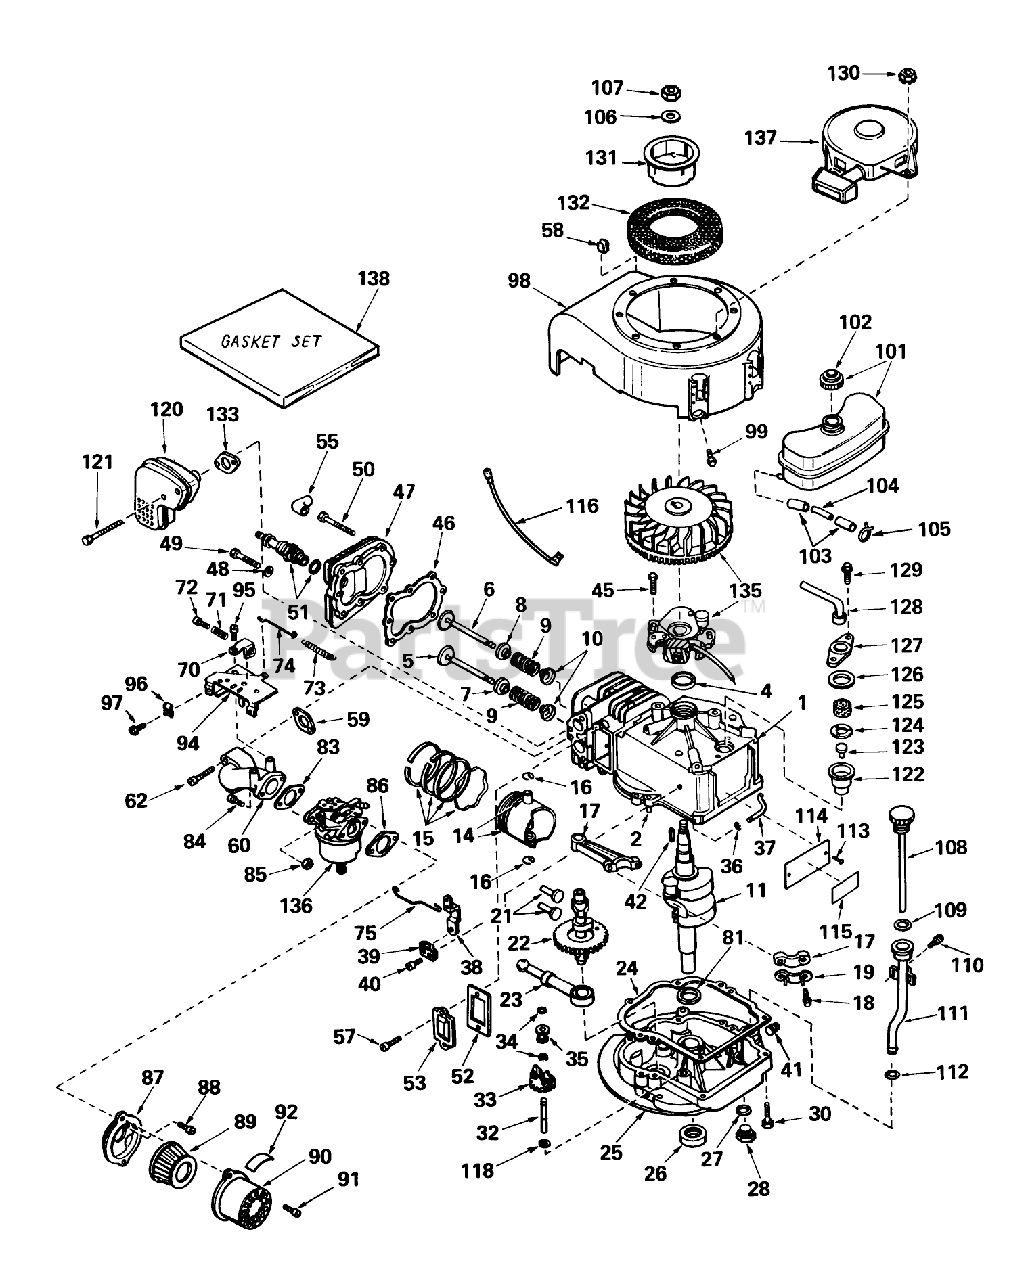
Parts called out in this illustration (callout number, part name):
1	Cylinder Assy. (Incl. Nos. 2 4)
2	Pin-Dowel
4	Seal-Oil
5	Valve, Intake (Standard) (Incl. Nos. 7, 9 10)
5	Valve, Intake (1/32" Oversize) (Incl. Nos. 7, 9 10)
6	Valve, Exhaust (Standard) (Incl. Nos. 8, 9 10)
6	Valve, Exhaust (1/32" Oversize) (Incl. Nos. 8, 9 10)
7	Cap-Upper Valve Spring
8	Cap, Upper Valve Spg (Exhaust)
9	Spring-Valve
10	Cap-Valve, Spring
11	Crankshaft
14	Piston Pin Assy. (Standard) (Incl. 2 of No. 16)
14	Piston Pin Assy. (.010 Oversize) (Incl. 2 of No. 16)
14	Piston Pin Assy. (.020 Oversize) (Incl. 2 of No. 16)
15	Ring Set-Piston Std.
15	Ring Set-Piston .010 oversize
15	Ring Set-Piston .020 oversize
16	Ring-Retaining, Piston Pin
17	Rod Assy., Connecting (Incl. Nos. 18 19)
18	Connecting Rod Bolt
19	Plate Lock
21	Lifter-Valve
22	Camshaft (Compr. Release)
23	Oil Pump ASM
24	Gasket, Mounting
25	Flange Assy., Mounting (Incl. Nos. 26, 27, 28 32)
26	Seal-Oil
27	Gasket-Oil Drain
28	Plug, Drain
30	Screw (1/4-20 x 1-1/4)
32	Shaft-Governor
33	Governor Gear ASM
34	Ring-Retaining
35	Spool-Governor
36	Washer-Flat
37	Rod, Governor (Incl. No. 36)
38	Governor Lever
39	Clamp-Lever, Governor
40	Screw
41	Plug-Pipe
42	Key Flywheel
45	Screw
46	Oil Fill Tube
47	Head Cylinder
48	Washer
49	Screw
50	Screw Hex Hd. Cap
51	Plug, Spark (J17LM or equiv.)
52	Gasket-Breather
53	Cover-Valve
55	Cover-Spark Plug
57	Screw
58	51004 GIL ROTARY TI
59	Gasket, Intake
60	Pipe, Intake
62	Screw, Fil. Slotted Hd.Sems
70	Brachet, Control
71	Spring
72	Screw, Hex Hd.
73	Spring, Governor
74	Link Governor Spring
75	Link Governor
81	Washer-Thrust
83	Gasket
85	Nut and Lock Washer (1/4-28)
86	Gasket
87	Bracket
88	Screw (10-32 x 1/2)
89	Element
90	Body
91	Screw
92	Decal
94	Control Assy., Speed
95	Screw (10-24 x 9/16)
96	Conduit
97	Screw (10-32 x 3/8)
98	Housing, Blower
99	Screw (1/4-20x19/32)
101	Tank Assy., Fuel (Incl. No. 102)
102	Cap, Fuel
103	Line-Fuel (8.62)
104	Line, Fuel
105	Clamp-Line, Fuel
106	Washer-Spring
107	Hex Nut
108	Dipstick, Assy., Oil (Incl. No.109)
109	O-Ring
110	Screw (10-32 x 1/2)
111	Tube Assy., Oil Fill
112	O-Ring
113	Stud
114	IDENTIFICATION PLATE
115	480B GIL SNWTHWR O/
116	SPOOL RETAINER (10-PK)
118	Washer-Flat
120	Muffler
121	Screw-Fil. Hd.
122	Body Breather Tube
123	Valve Check
124	2000A37 WIZARD ROTA
125	Element-Breather
126	Gasket-Breather
127	Cover Breather
128	Tube, Breather
129	Screw, Hex Hd. w/Conical
130	Nut and Lock Washer (1/4-28)
131	Cup, Starter
132	Screen-Starter
133	Gasket-Exhaust
135	Magneto
136	Carburetor
137	Starter, Rewind
138	Gasket Set
